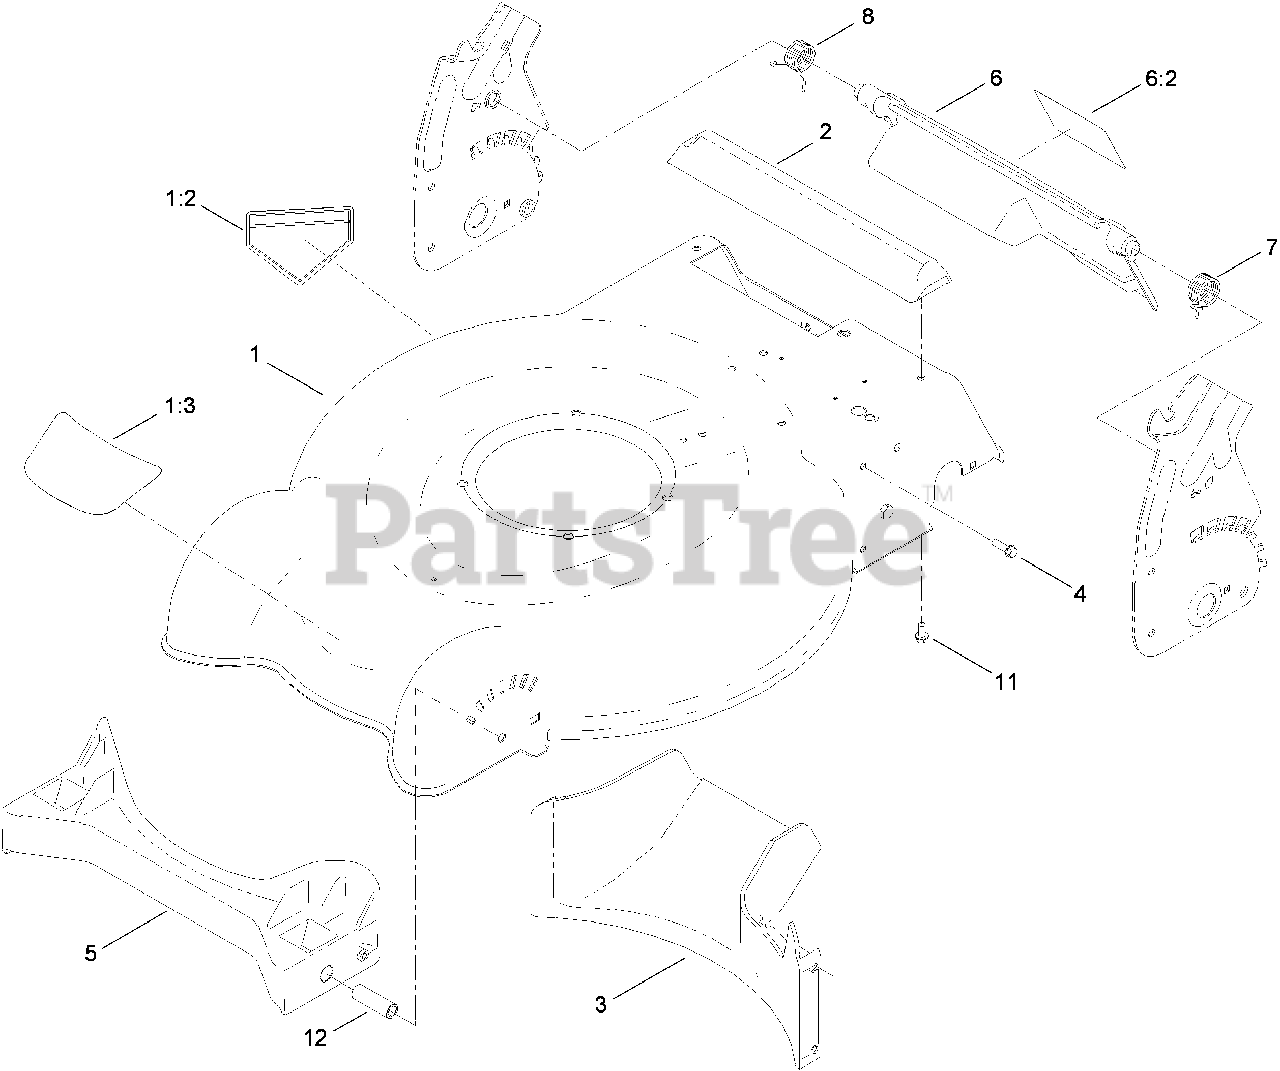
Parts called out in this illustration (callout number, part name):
1	HOUSING ASM
1:2	DECAL-DANGER
2	CHUTE-REAR
3	BAFFLE-REAR
4	SCREW-HWH
5	BAFFLE-FRONT
6	Rear Deflector ASM
6:2	DECAL-WARNING, CE
7	SPRING-TORSION, LH
8	SPRING-TORSION, RH
11	SCREW-PLASTITE
12	SPACER-BAFFLE, FRONT
